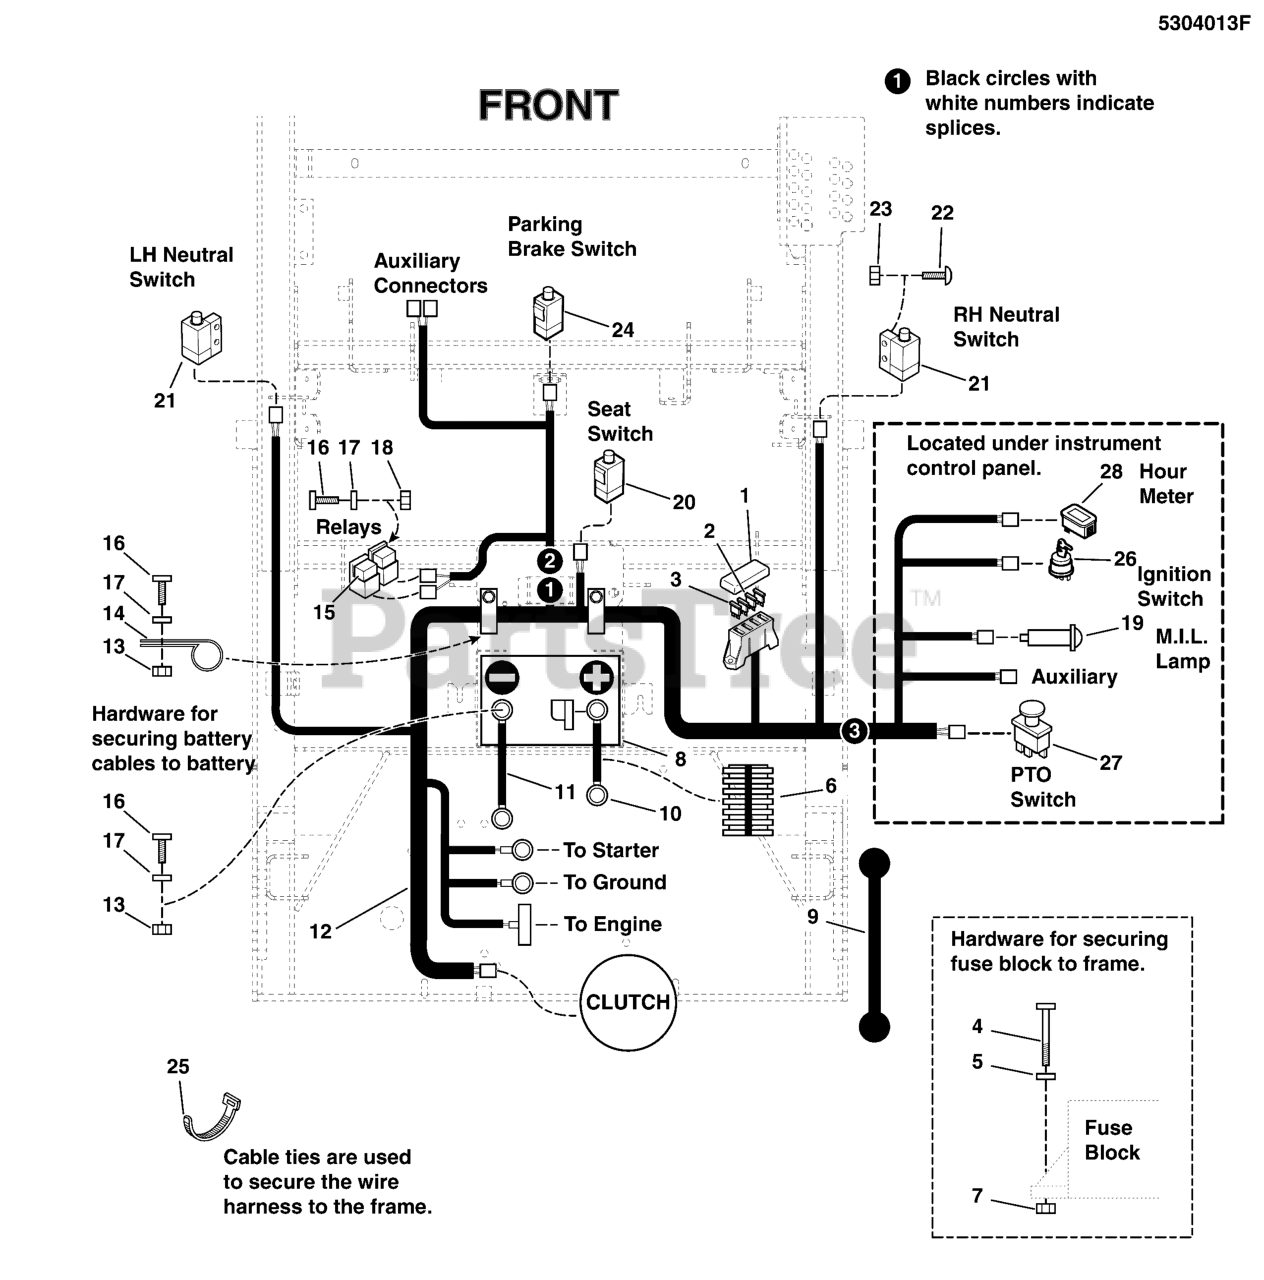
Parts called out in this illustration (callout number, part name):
1	COVER, VINYL FUSEBLOCK
2	FUSE, ATO-15 (15 AMP)(SV)
3	FUSE, ATO-20 (20 AMP)(SV)
4	SCREW, #10-24 X 2 ROUND PHILLIPS
5	WASHER, #10 SAE
6	WIRE LOOM, 3/8 ID X 17 IN
7	NUT, #10-24 HEX NYLON LOCK
8	BATTERY, WET ( BCIU1, 350 CCA)
9	STRAP-BLACK RUBB
10	BATTERY CABLE, NEG, 14, 5/16-13/32
11	BATTERY CABLE, POS, 22, 1/4-5/16
12	WIRE HARNESS, S200XT, B&S EFI
13	NUT, 1/4-20 HEX NYLOCK FLANGE
14	CLAMP, VINYL INSULATED
15	RELAY, 12V, 40A
16	BOLT, 1/4-20 X 3/4 GD5 CZ
17	WASHER, 1/4 SAE
18	NUT, 1/4-20 HEX SERR. FLANGE
19	LAMP, MALFUNCTION INDICATOR LAMP (M.I.L.) (SEE INSTRUMENT CONTROL PANEL GROUP)
20	SWITCH, PLUNGER, NO, SINGLE POLE, SNAP-IN
21	SWITCH, PLUNGER, N.O.
22	SCREW, #10-24 X 3/4 ROUND PHILLIPS
23	NUT, #10-24 HEX
24	SWITCH, DP NO/NC SNAP-IN
25	TIE, SELF-LOCKING, 12"
26	SWITCH, IGNITION, 6 POST (SEE INSTRUMENT CONTROL PANEL GROUP)
27	SWITCH, BLADE ENGAGEMENT (SEE INSTRUMENT CONTROL PANEL GROUP)
28	HOUR METER (SEE INSTRUMENT CONTROL PANEL GROUP)
